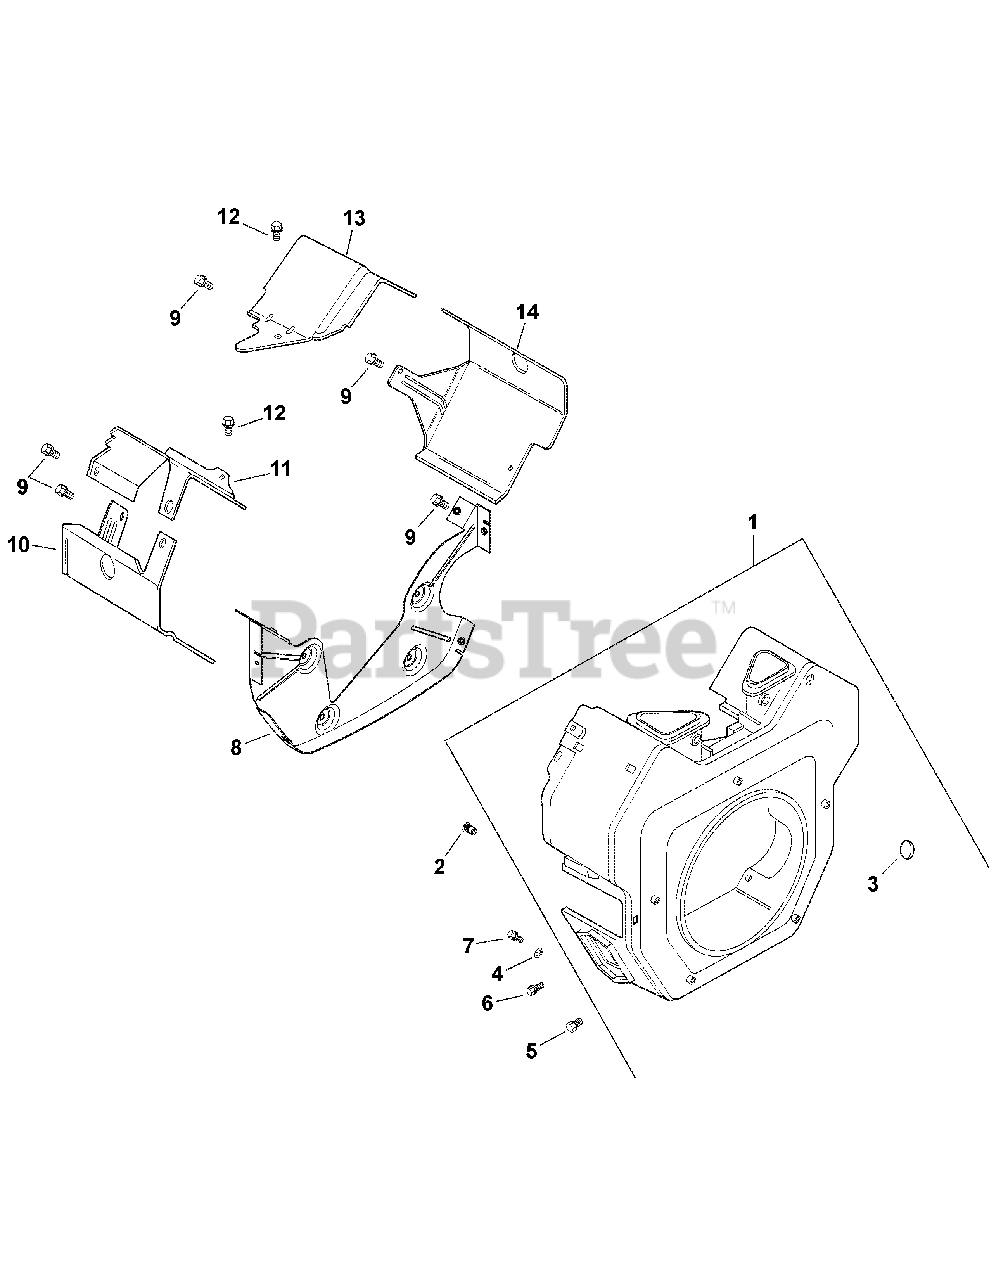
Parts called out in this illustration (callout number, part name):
1	Housing, blower (Includes 2, KH-41-037-10-S)
2	Insert, threaded (5)
4	Washer, flat, 7/32" (2)
5	Screw, hex. Flange M5x0.8x16
6	Screw, hex. Flange M5x0.8x16 (3)
7	Screw, hex. Flange M5x0.8x20 (4)
8	Plate, backing (Includes KH-25-154-11-S)
9	Screw, hex. flange (6) M6x1.0x16 (6)
10	Baffle, cyl barrel #2 side
11	Baffle, valley - #2 side
12	Screw, hex. Flange M5x0.8x10 (2)
13	Baffle, valley - #1 side
14	Baffle, cylinder barrel - #1 side
